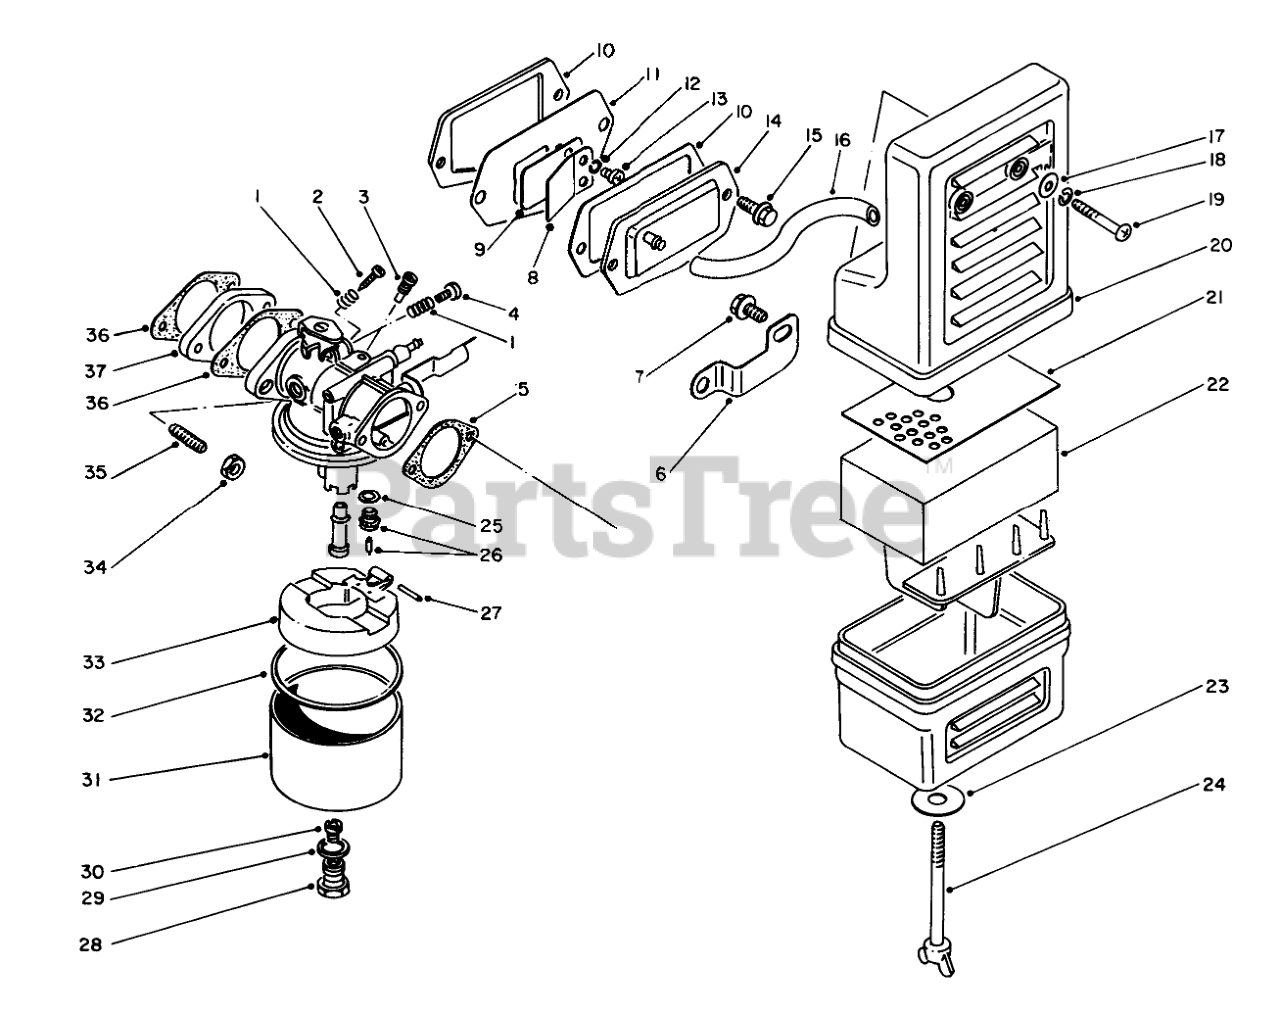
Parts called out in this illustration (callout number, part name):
1	SPRING-PILOT SCREW
2	ADJUSTER
3	PILOT JET
4	SCREW
5	AIR CLEANER GASKET
6	AIR CLEANER BRKT
8	Stopper
9	Reed Valve
10	Gasket
11	Reed Valve Assembly (Incl . Ref . #8-10)
12	Lockwasher
14	Cap-Breather
17	WASHER
18	Washer
19	SCREW
20	AIR CLEANER ASM
21	Holder
22	FILTER
23	WASHER
24	Bolt-Wing
25	GASKET
26	NEEDLE VALVE
29	GASKET
30	MAIN JET
31	Carburetor Assembly (Incl. Ref. #25-30 & 32 & 33)
32	GASKET
33	FLOAT
35	Bolt-Stud
36	Gasket
37	INSULATOR
